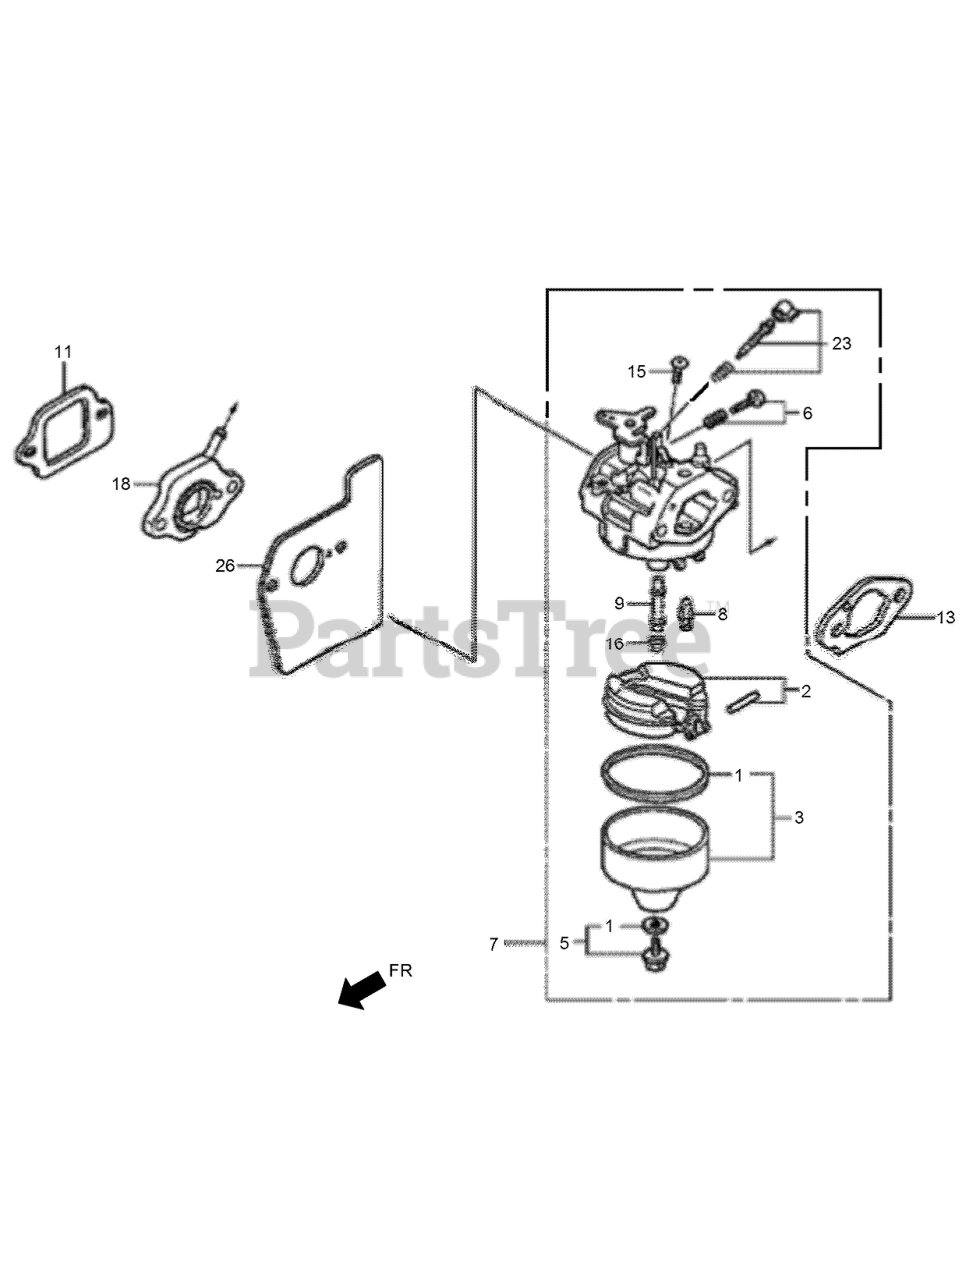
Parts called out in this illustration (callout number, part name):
1	PACKING SET
2	FLOAT SET
3	CHAMBER SET-FLOAT
5	SCREW SET
6	SCREW SET
7	CARBURETOR ASM (BB62Y B) (to S/N 3276088)
7	CARBURETOR ASM (BB62Y C) (from S/N 3276089 to 3406723)
7	CARBURETOR ASM (BB65V A) (from S/N 3406724)
8	VALVE-FLOAT
9	NOZZLE-MAIN (BB65V A)
9	NOZZLE-MAIN (BB62W C)
11	PACKING-INSULATOR
13	PACKING-CARBURETOR
15	SCREW-PAN-5X6
16	JET-MAIN NO. 62
16	JET-MAIN NO. 65
18	CARBURETOR INSULATOR ASM
23	SCREW SET
26	GUIDE-AIR
